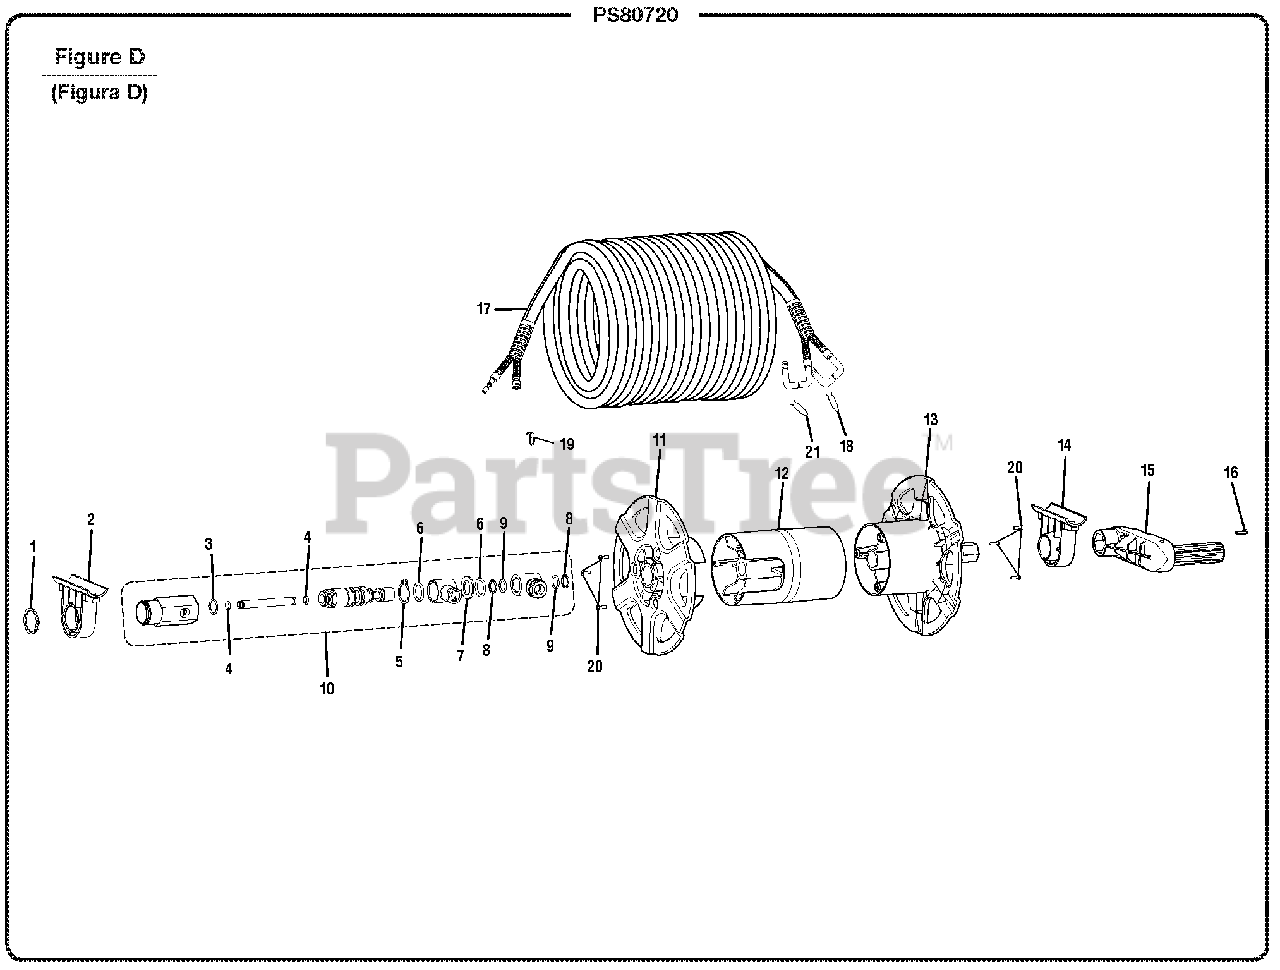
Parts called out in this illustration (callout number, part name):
1	Retaining Ring
2	Mounting Bracket (Left)
5	Retaining Ring
7	Washer (ID16.2 x OD28 x 2.5t)
8	Backup Ring (ID13 x OD16 x 1.4t)
10	Water Inlet
11	Cover (Left)
12	Middle Body
13	Cover (Right)
14	Mounting Bracket (Right)
15	Handle Assembly
16	Screw (M4 x 12 mm, Pan Hd.)
18	Low Pressure Hose Clip
19	Low Pressure Trigger Handle Clip
20	Screw (M3 x 10 mm)
21	High Pressure Hose Clip
